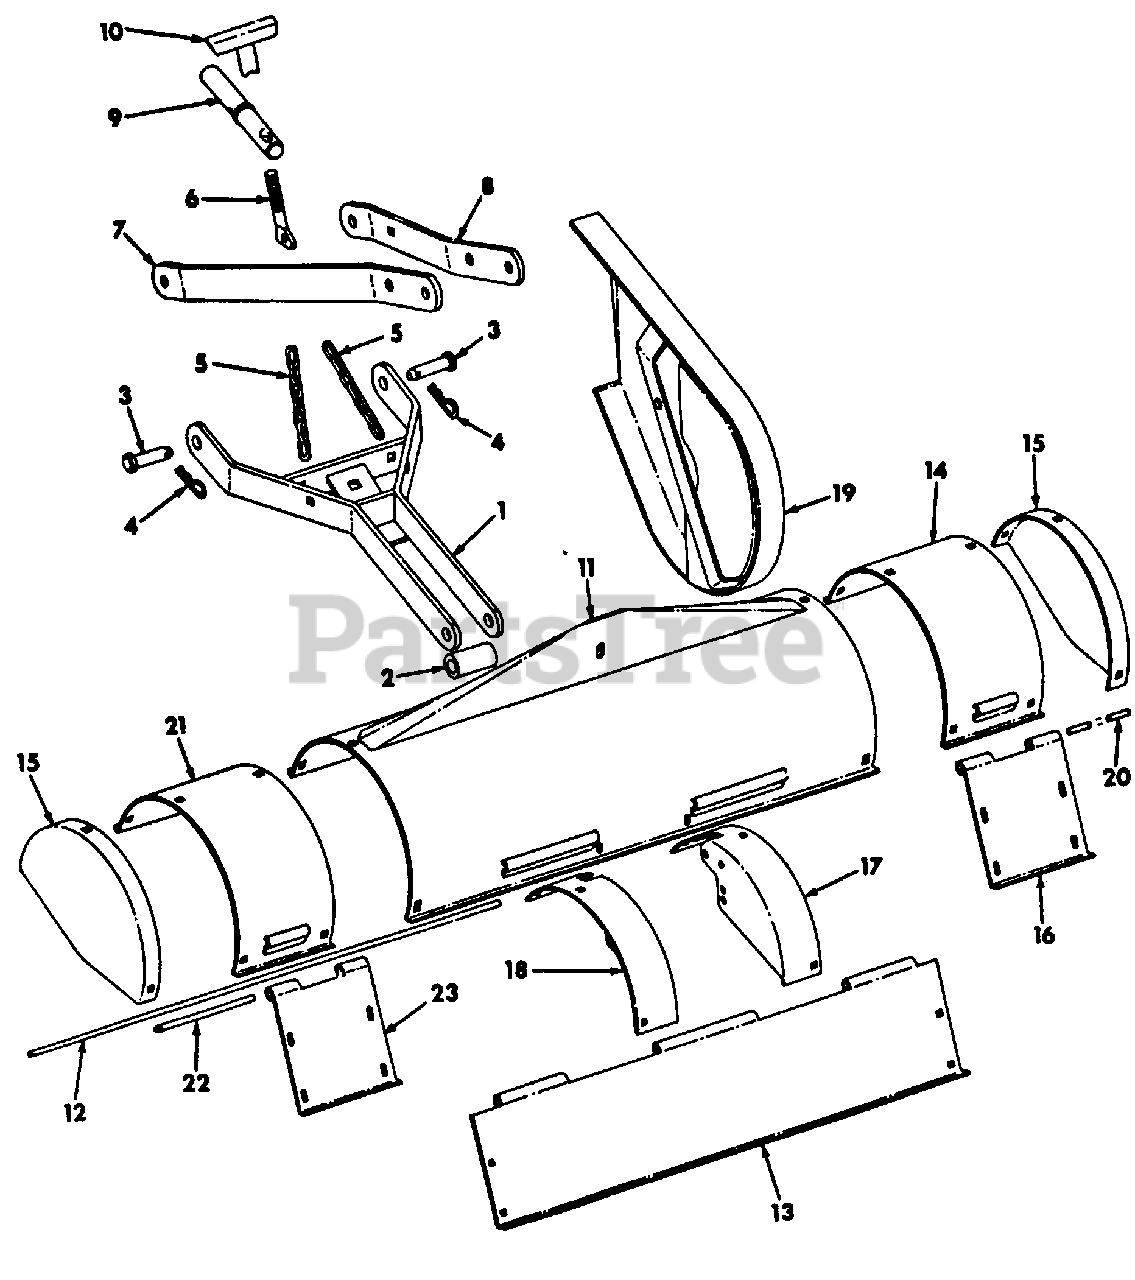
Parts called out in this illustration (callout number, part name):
1	Bracket Assy, Lower Support
2	Bushing, Pivot
3	Pin, Clevis
4	Pin, Quick Attaching Cot
5	Chain, Lift
6	Rod, Adjustment
7	Bar, Support LH
8	Bar, Support RH
9	Shaft Assy, Support
10	Tee Assy, Depth Control
11	Shield Assy, Safety
13	Plate, Back
14	Shield Assy, Extension
16	Plate, Extension
17	Shield, Mounting Bracket RH
18	Shield, Mounting Bracket LH
19	Guard Assy, Belt
21	Shield Assy, Extension
22	Rod, Pivot
23	Plate, Extension
